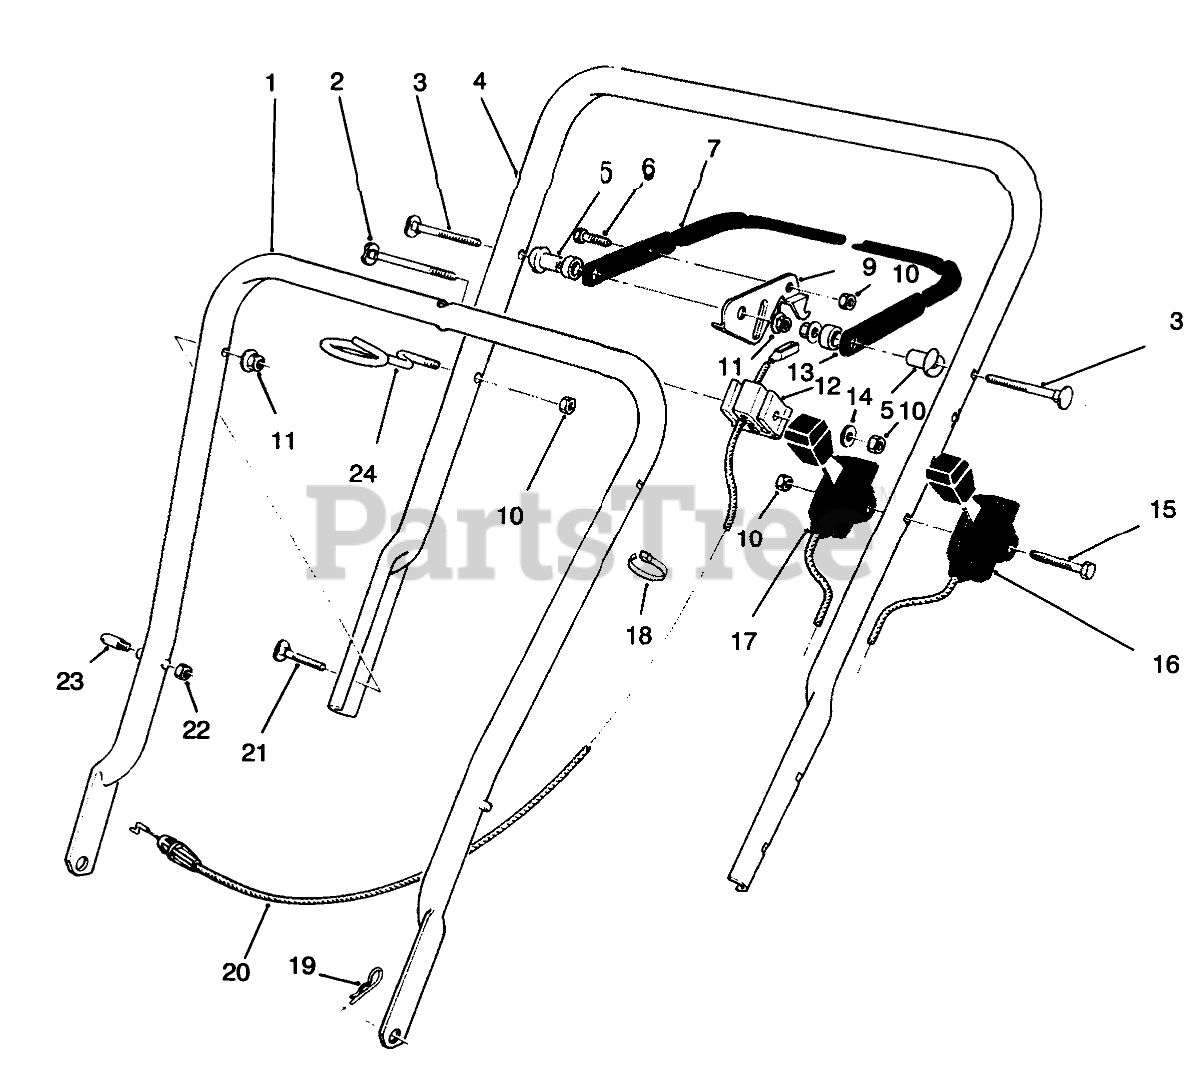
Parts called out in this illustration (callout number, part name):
1	Lower Handle Assembly
2	SCREW-HANDLE
3	SCREW-HANDLE
4	UPPER HANDLE
5	SPACER-SUPPORT
6	SCREW-HH
7	Bar-Control
9	CONTROL LEVER
10	NUT-LOCK, NI
11	NUT-LOCK NI
12	SUPPORT-CABLE
13	SPACER-NYLON
14	WASHER-FLAT
15	SCREW-HH
16	TRACTION CONTROL
17	THROTTLE CONTROL
18	TIE-CABLE
19	PIN-COTTER, HAIR
20	BRAKE CONTROL CABLE
21	SCREW-HANDLE
22	NUT-LOCK, NI
23	HANDLE PIN
24	GUIDE-ROPE
